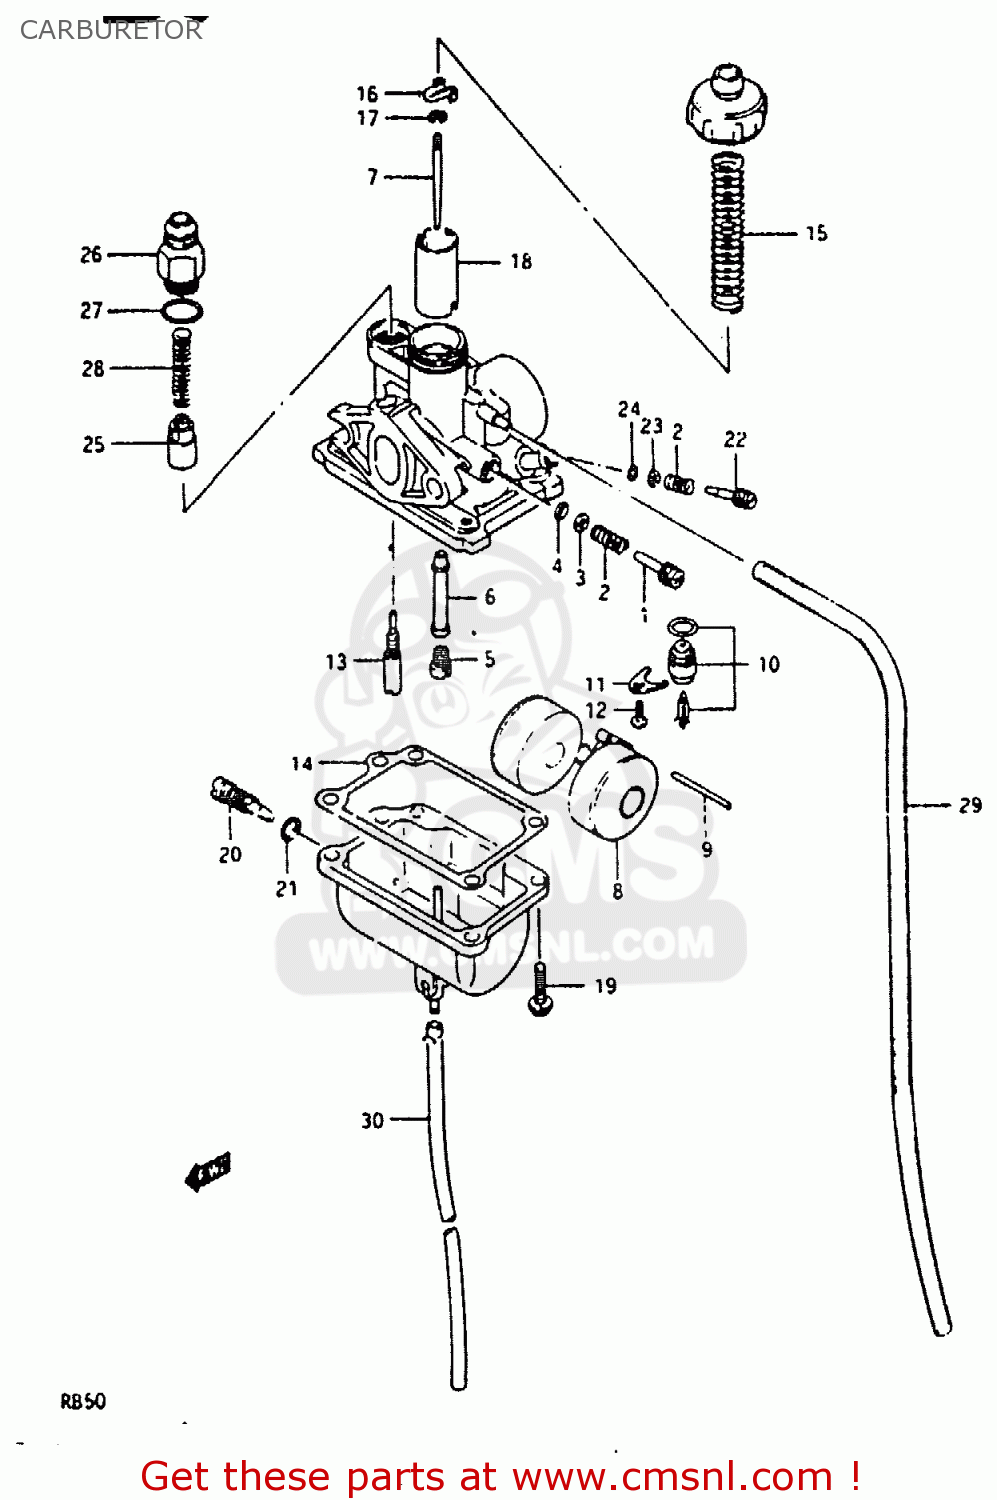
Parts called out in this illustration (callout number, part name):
1	SCREW,THROTTLE STOP
2	SPRING
3	WASHER
4	O RING
5	JET,MAIN(80)
6	JET,NEEDLE (E-5)
7	NEEDLE JET
8	FLOAT
9	PIN,FLOAT
10	VALVE ASSEMBLY,NEEDLE
11	PLATE,NEEDLE VALVE FITING
12	SCREW
13	JET,PILOT(15)
14	GASKET (NAS)
15	SPRING,THROTTLE VALVE
16	SEAT,THROTTLE VALVE SPRING
17	CLIP,NEEDLE
18	VALVE,THROTTLE
19	SCREW
20	PLUG,DRAIN
21	O RING
22	SCREW,PILOT AIR
23	GASKET
24	O RING,PILOT AIR SCREW
25	PLUNGER,STARTER
26	CAP,STARTER
27	O RING
28	SPRING
29	HOSE
30	HOSE (3X5X475)
